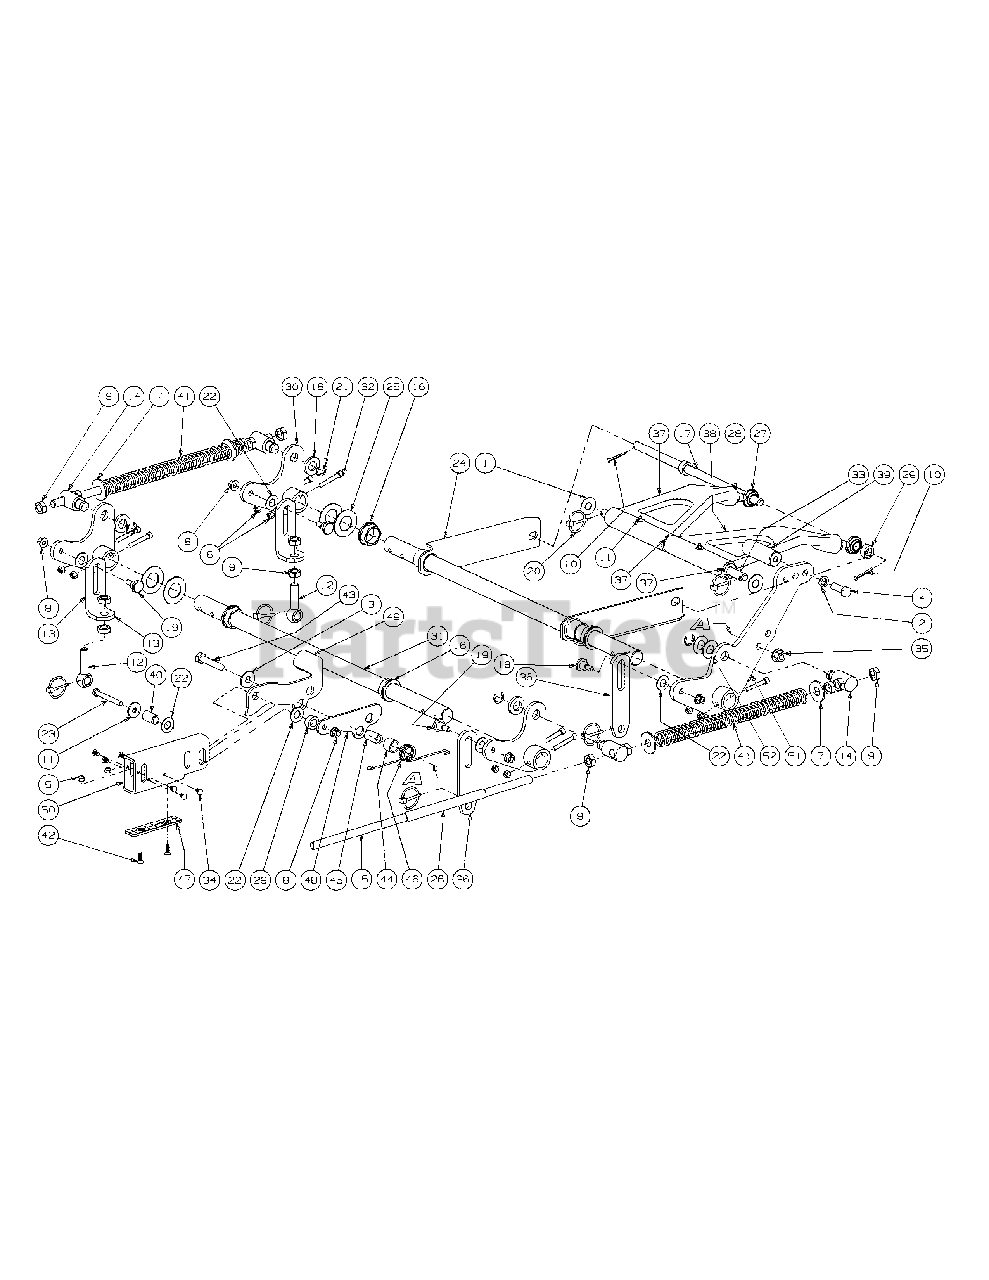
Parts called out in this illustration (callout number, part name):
1	Washer, 1.5 x .655 x .055
2	Lock Washer, 1/2
3	Flat Washer, .536 ID x .930 OD x .05
4	Hex Cap Screw, 1/2-13 x 1.50
5	Lock Nut w/Nylon Insert
6	Nut, 5/16-18, Nylock
7	Flat Washer, 5/8
8	Hex Nut, Flange Lock, 3/8-16
9	Jam Nut, 5/8-11
10	Cotter Pin, 3/16 x 1-1
11	Flat Washer, 1.25 x .411 x .100
12	Eye Bolt, 5/8ID
13	Eye Bolt Mount Link, 5/8 ID
14	Ferule Lift
15	Lift Connector Rod
16	Hex Flange Bearing, 1.25 ID
17	Front Lift Link, Rod Mount
18	Spacer, .812 ID x .268 Lg.
19	Shoulder Screw, 0.625 OD x .437 Lg.
20	Linch Pin, 3/16 Dia.
21	E Clip, 3/4 Dia.
22	Nylon Flat Washer, 5/8
23	HHCS, 3/8-16, 3.00
24	Front Frame Strut Assembly
25	Flat Washer, 1.25 ID
26	Hose, 5/8 ID 13/16 OD, 8" LG
27	Rod End, Male
28	Jam Nut, 5/8-18
29	Spacer, .630 ID x 1.06 OD x .440
30	Bellecrank Weldment Assembly
31	Deck Lift Shaft
32	Socket Head CapScrew, 5/16-18 x 2
33	Lift Link Rod
34	Rivet, 1/4 x 5/8
35	Nut, 1/2-13, FlangeLock
37	Bearing Lift Brace Assembly, Left Hand includes:
37	Grease Fitting
38	Bearing Lift Brace Assembly, Right Hand includes:
38	Grease Fitting
39	Deck Lift Foot Pedal
40	Spacer, .375 ID x .625 OD x 2.20
41	Lift Compression Spring
42	Flat Head Cap Screw, 1/4-20 x .75
43	Socket Head Cap Screw, 1/2-13 x 2.50
44	Spacer, .76 ID x 1.0 OD x .75
45	Spacer, .51 ID x .75 OD x 1.240
46	Torsion Spring, .120 Wire x 1.32 OD
47	Lift Wear Plate
49	Lift Link Bracket
50	Lift Tube, 3.0 x 1.5
51	Deck Lift Foot Pedal Weldment
52	Washer, .76 x 1.49 x .06
